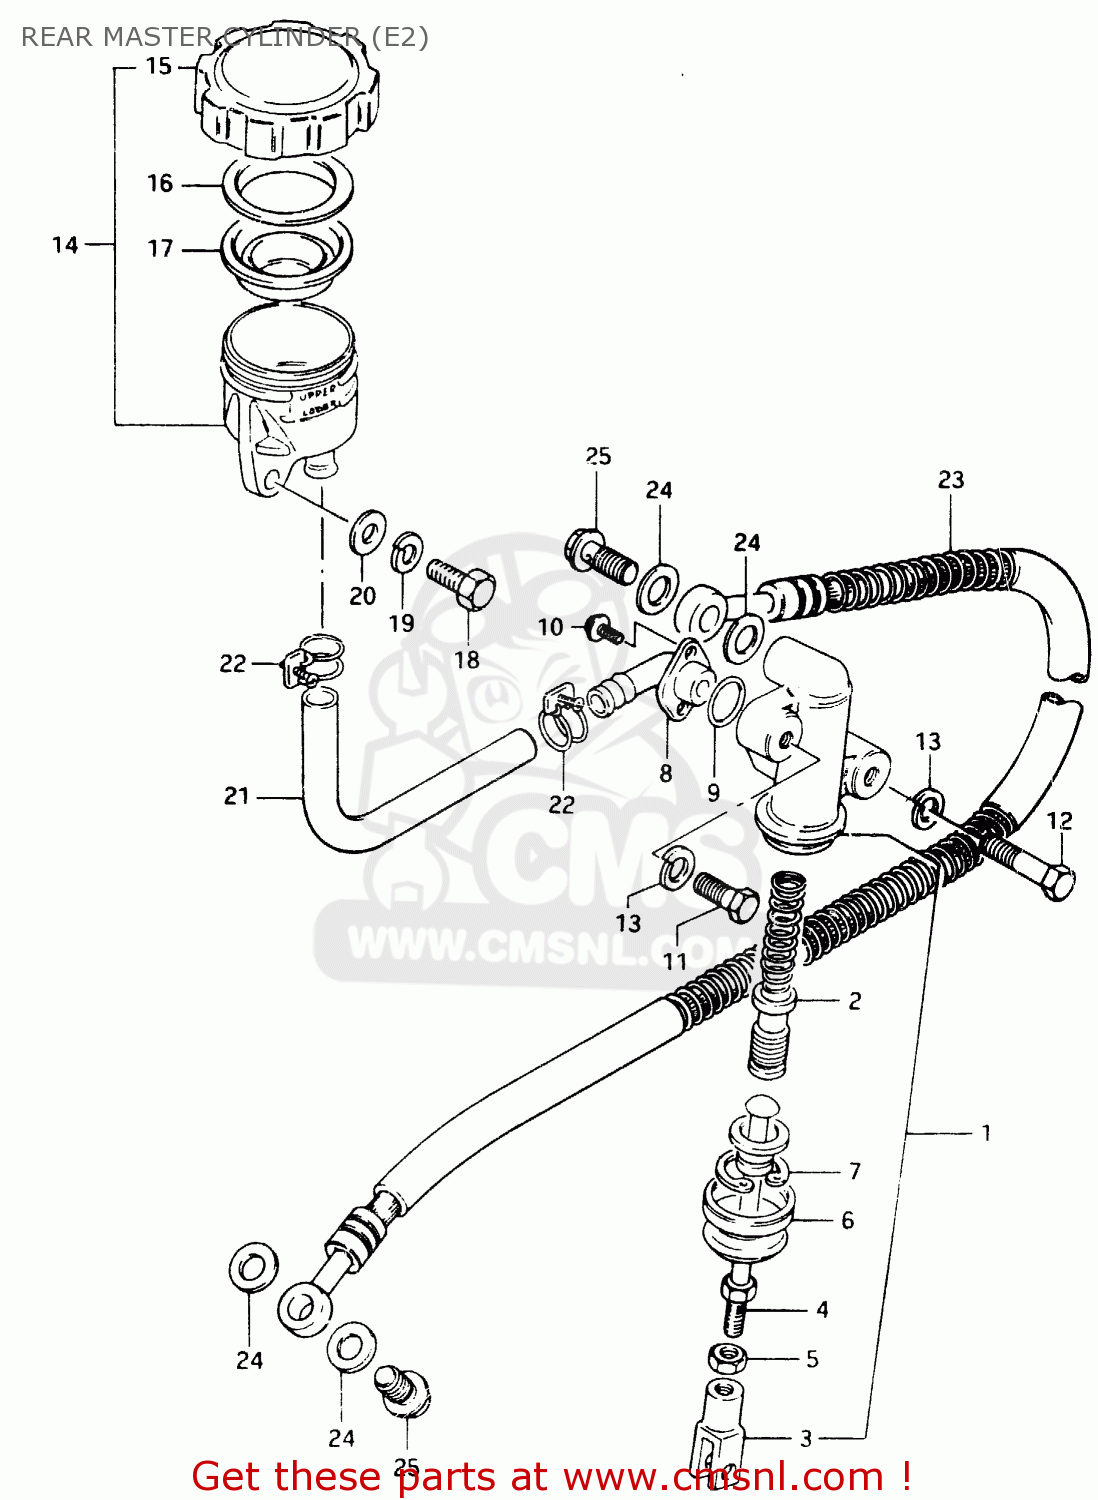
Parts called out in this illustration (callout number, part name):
1	CYLINDER ASSEMBLY,REAR MASTER
2	PISTON/CUP SET
3	YOKE
4	ROD,REAR MASTER CYLINDER
5	NUT,MASTER CYLINDER
6	BOOT
7	CIRCLIP
8	CONNECTOR,HOSE
9	O RING
10	SCREW
11	BOLT
12	BOLT 8X55
13	LOCK WASHER
14	TANK ASSEMBLY,RESERVOIR
15	CAP
16	PLATE,DIAPHRAGM
17	DIAPHRAGM
18	BOLT, UPPER
19	LOCK WASHER
20	WASHER
21	HOSE
22	CLAMP
23	HOSE, REAR BRAKE
24	WASHER
25	BOLT UNION
